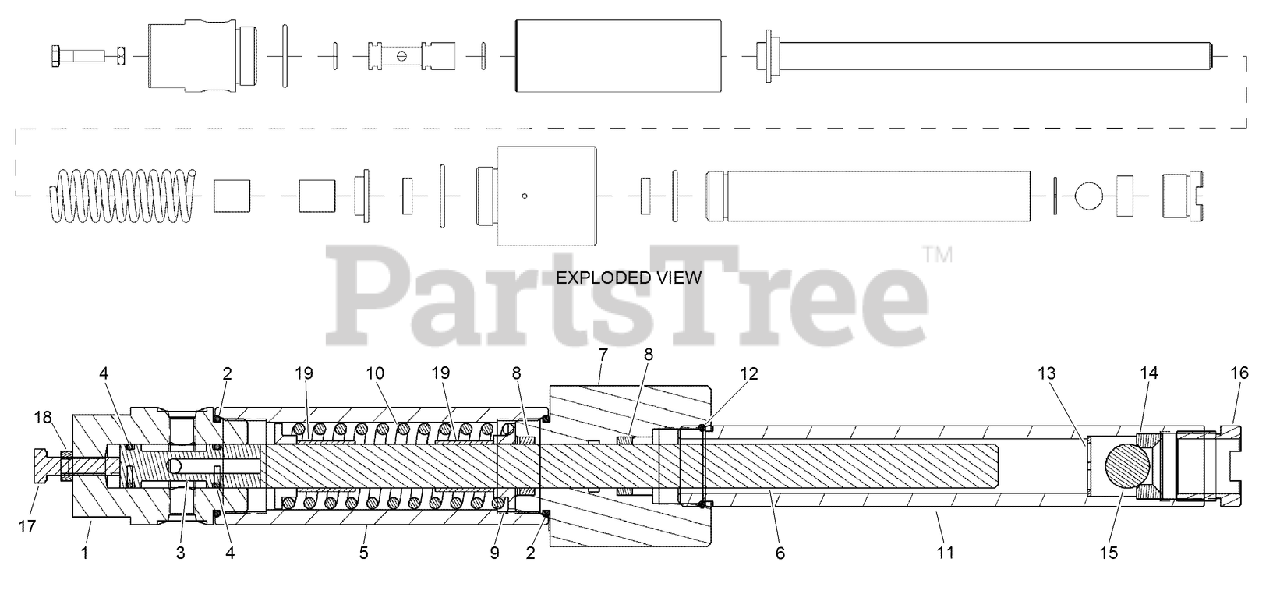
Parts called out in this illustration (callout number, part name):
1	CAP - Cylinder
2	SEAL-O RING
3	SPOOL-ADJUSTING
5	BARREL - Cylinder
6	PLUNGER
7	BODY - Pump
8	SEAL-DEEP
9	GUIDE-ROD
10	SPRING
11	BARREL-PUMP
12	SEAL-O RING
13	CLIP-RETAINER
14	VALVE-SEAT
15	BALL-STEEL, STAINLESS
16	TUBE-INLET
17	BOLT-Hex, 5/16 NC x 1-1/4 inch
18	NUT - Hex Jam 5/16-18 GR5 ZND
19	BEARING - Sleeve, Bronze
